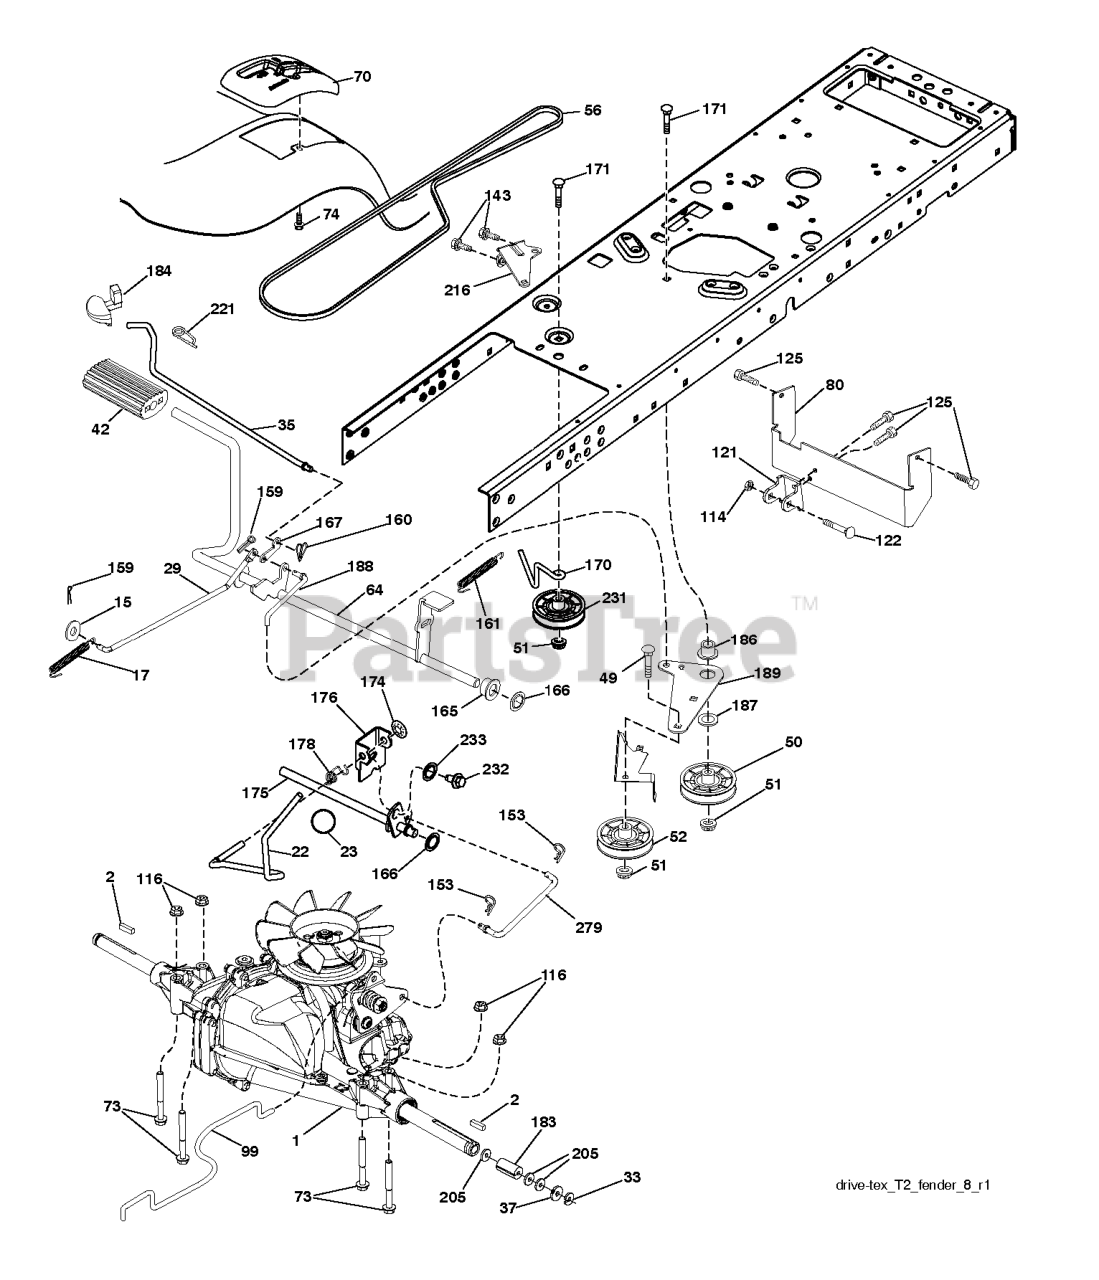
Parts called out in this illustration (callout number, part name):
2	SQUARE KEY
15	WASHER
17	SPRING.BRAKE.HG3000/3500
22	ROD.SHIFT.FENDER.TLT.2006
23	KNOB.DUCKHEAD.1/2
29	ROD.BRAKE.T2.TEX
35	ROD.CNTRL.PARK.PREDATOR.LT.TEX
42	PEDAL COVER T
50	IDLER.FLAT.910.OFFSET
51	NUT LOCK FLG 3/8-16 UNC
52	IDLER.V-GROOVE.910.OFFSET
64	SHAFT.ASM.PEDAL.BRAKE.
70	CONSOLE SHIFT
73	BOLT HEX 5/16-18 GR 5
74	SCREW.HI-LO.CONSOLE
80	RP.STRAP.TORQUE.FS.T2
99	ROD.ASM.BYPASS.SPRING.T2.FS
114	NUT.71038.31-18.HEX.NYLOCK
116	NUT LOCK HEX FLANGE 5/16-18
121	BRACKET STRAP TORQUE
122	BOLT.5/16-18X2.5
125	SCREW
143	Screw 5/16-18 x 1/2 Hex, Self Tapping 5/16-18 x 1/2
153	RETAINER M
159	COTTER PIN
160	RETAINER CLIP
161	SPRING, RETURN LT
165	BUSHING.SHAFT.BRAKE.HAND
166	NUT.PUSH.625.2006
167	LATCH.BRAKE.SPRING
170	KEEPER.CENTER SPAN.1.688
174	NUT.PUSH.500.2006
175	SHAFT.ASM.SHFT.T2.TLT
176	ARM.CLEVIS.ROD.SHIFT
178	SPRING.SHIFT.GT2006
183	SPACER, AXLE PVST
184	HANDLE PARKING BRAKE
186	SPACER.RETAINER
187	WASHER 12/32X2X10GA
188	RP.LINK.CLUTCH.GROUND.DRIVE
189	BELLCRANK.GROUND.DRIVE.TEX.
190	KEEPER.BELLCRANK.DRIVE
216	BRACKET.PULLEY.IDLER.W/TEX
221	RETAINER.SPRING.CLIP.H
231	IDLER.V-GROOVE.1.688.OFFSET
232	BOLT FIN HEX 7/16-14 X 1
233	WASHER SERRATED
279	LINK SHIFT
